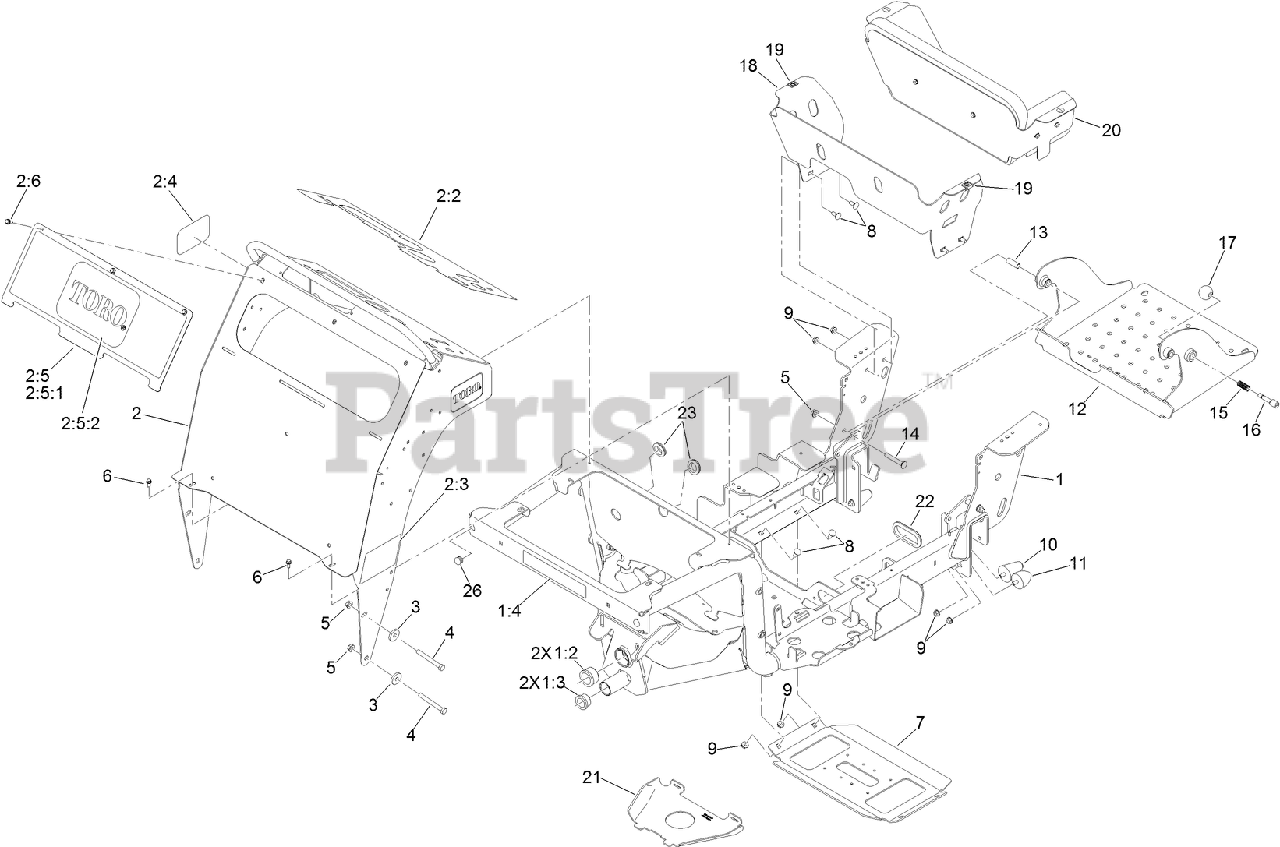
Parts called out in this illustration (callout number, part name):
1	FRAME ASM
1:2	BEARING-FLANGED
1:3	BEARING-FLANGED
1:4	DECAL-DOWN, TIE
2	CONTROL TOWER ASM
2:2	DECAL-CONTROL
2:3	DECAL-SERVICE AID
2:4	DECAL-LOGO, TORO
2:5	ACCESS PANEL W/ DECAL
2:5:1	PANEL-ACCESS
2:5:2	DECAL-TORO
2:6	SCREW-HWH
3	WASHER
4	SCREW-HH
5	NUT-HF
6	SCREW-HWH
7	GUARD-LOWER
8	SCREW-CARR
9	NUT-HF
10	BUMPER-RUBBER
11	BUMPER-RUBBER
12	OPERATOR PLATFORM ASM
13	BUSHING-PIVOT, PLATFORM
14	SCREW-CARR
15	SPRING
16	PIN-LATCH
17	KNOB-BALL
18	MOUNT-PAD, KNEE
19	RECEPTACLE-CLIP, MINI
20	KNEE PAD ASM
21	SHIELD-DUST
22	GROMMET
23	GROMMET
26	PLUG-TUBE
